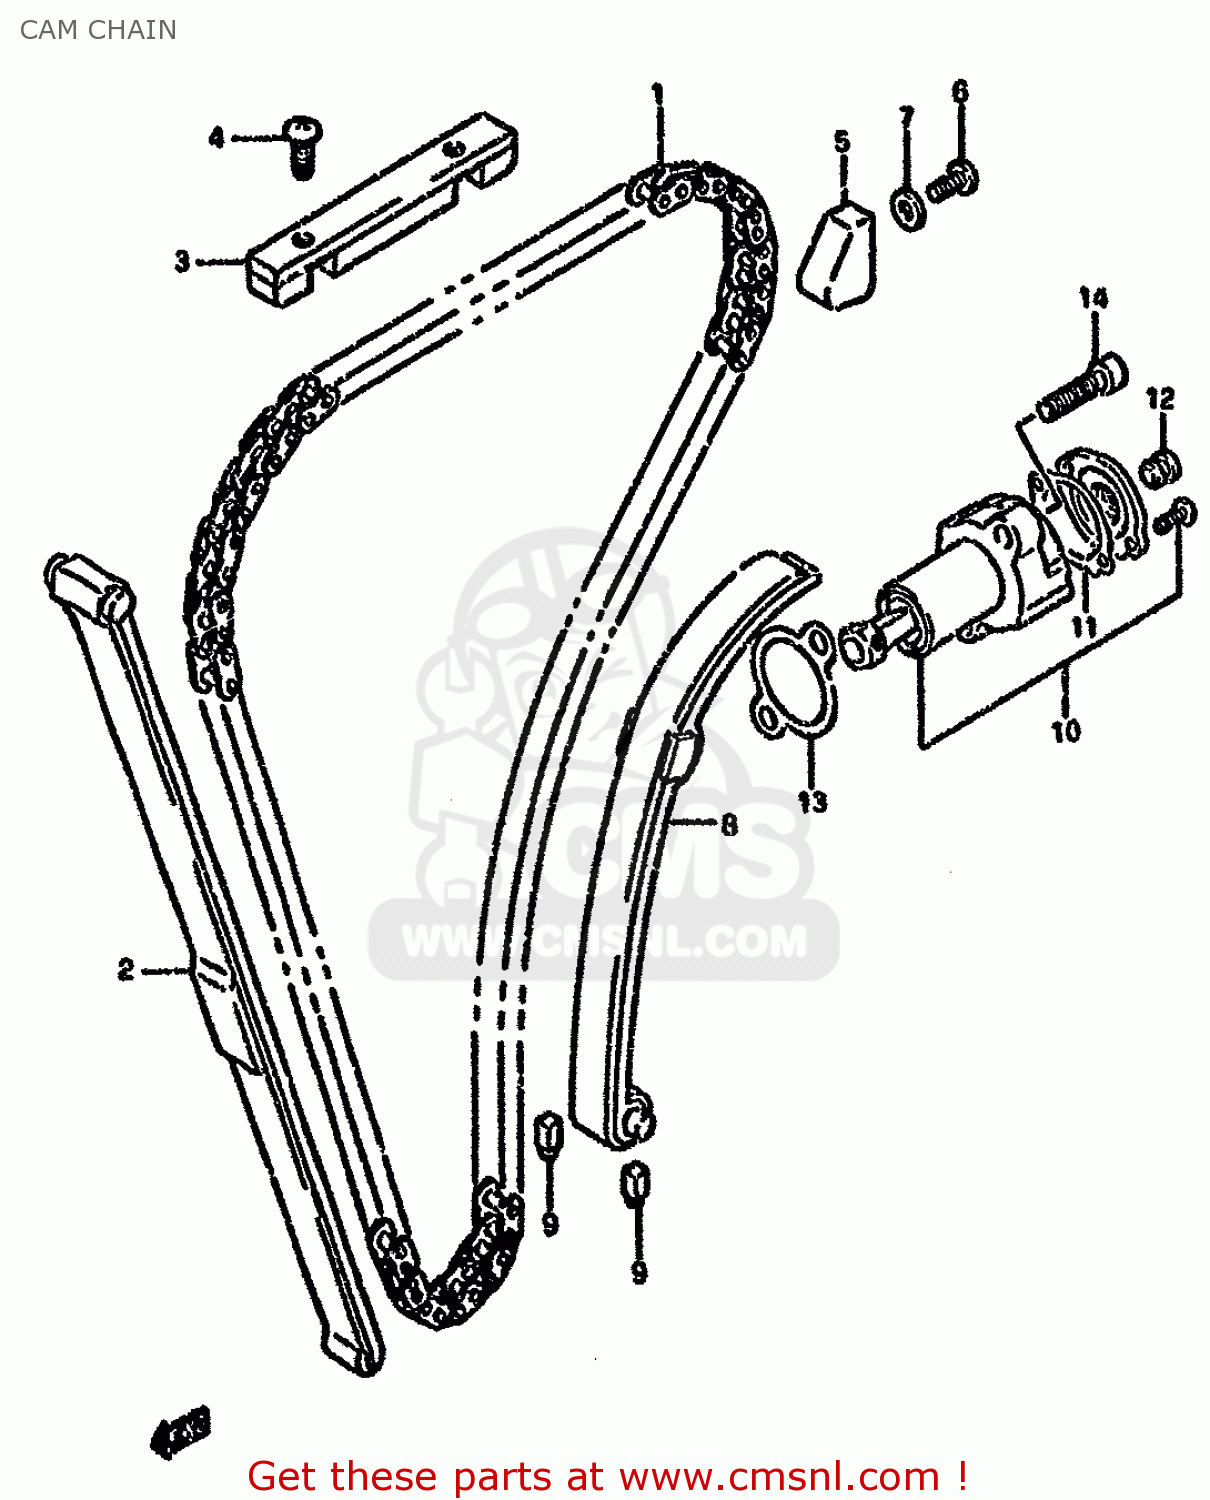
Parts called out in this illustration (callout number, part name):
1	CHAIN,CAMSHAFT DRIVE(120L)
2	GUIDE,CAM CHAIN NO.1
3	GUIDE,CAM CHAIN
4	SCREW
5	GUIDE,CAM CHAIN
6	BOLT
7	GASKET(5.8X13X1.2) (NAS)
8	TENSIONER,CAM CHAIN
9	CUSHION,CAM CHAIN TENSIONER
10	ADJUSTER ASSEMBLY,TENSIONER
11	GASKET,ADJUSTER CAP (NAS)
12	PLUG,ADJUSTER
13	GASKET,TENSIONER ADJUSTER (NAS)
14	BOLT
